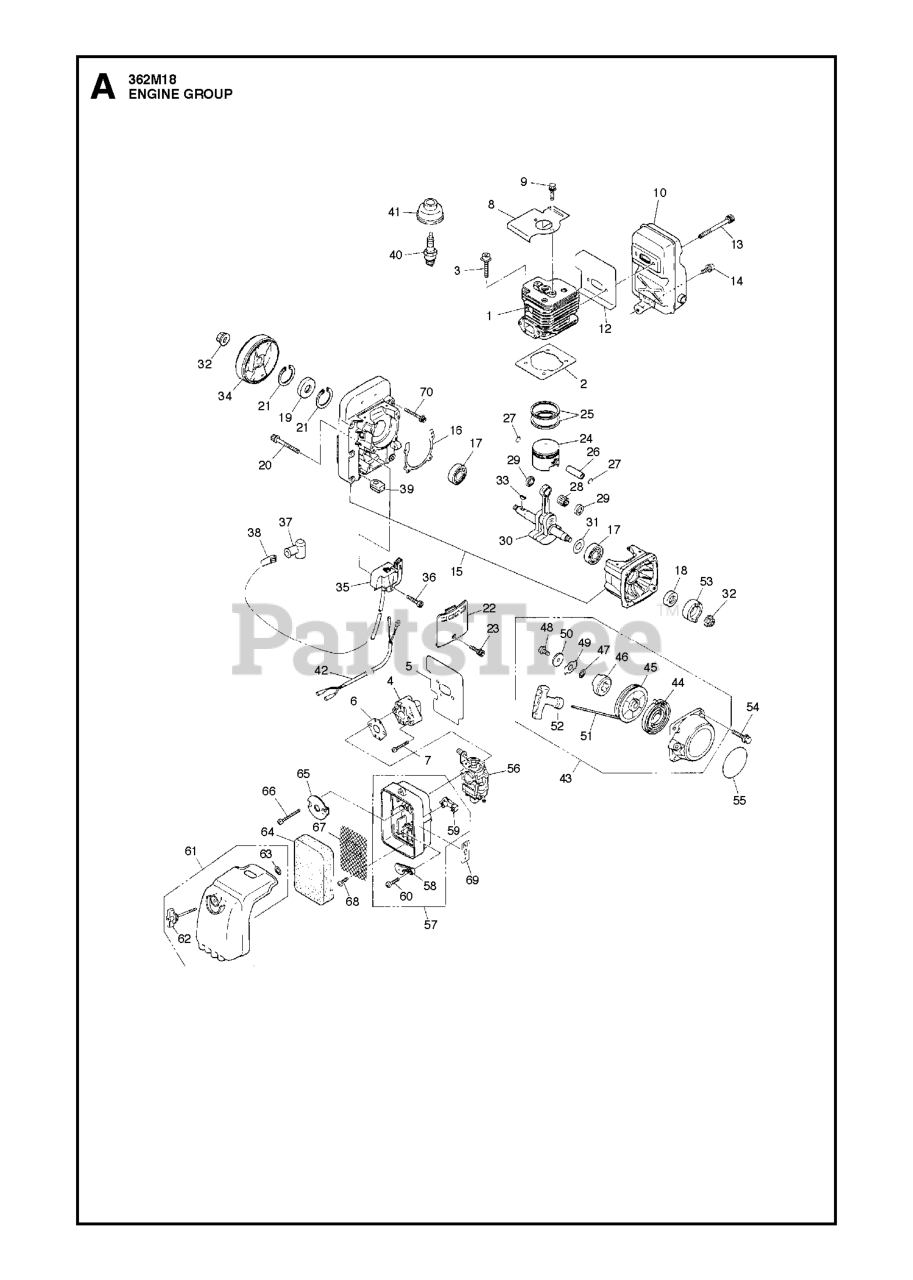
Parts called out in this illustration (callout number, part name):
10	MUFFLER
15	CRANKCASE COMP
25	RING.PISTON 2PK
30	CRANKSHAFT COMP. (RPLS. -4201)
39	GROMMET
43	STARTER ASSY
45	STARTER PULLEY
46	STARTER PAWL
49	RETAINER
50	WASHER
51	STARTER ROPE
56	CARBURETOR-A
60	SCREW
